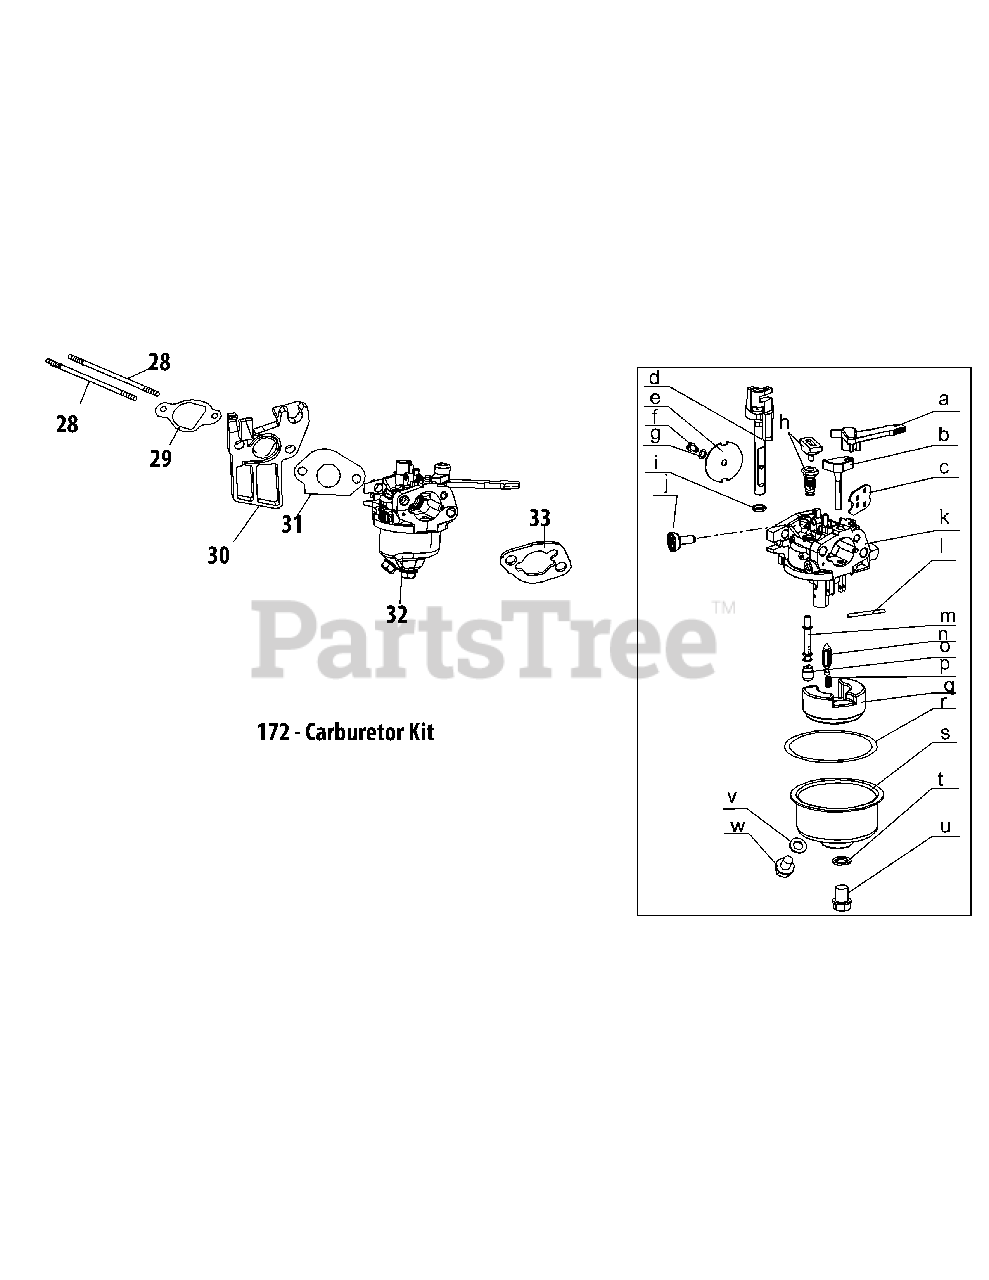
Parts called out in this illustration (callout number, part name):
28	Stud M6×110
29	CARBURETOR INSULATOR GASKET
30	CARBURETOR INSULATOR
31	CARBURETOR GASKET
32	Carburetor Assembly
33	CARBURETOR GASKET PLATE
172	Carb Repair Kit
